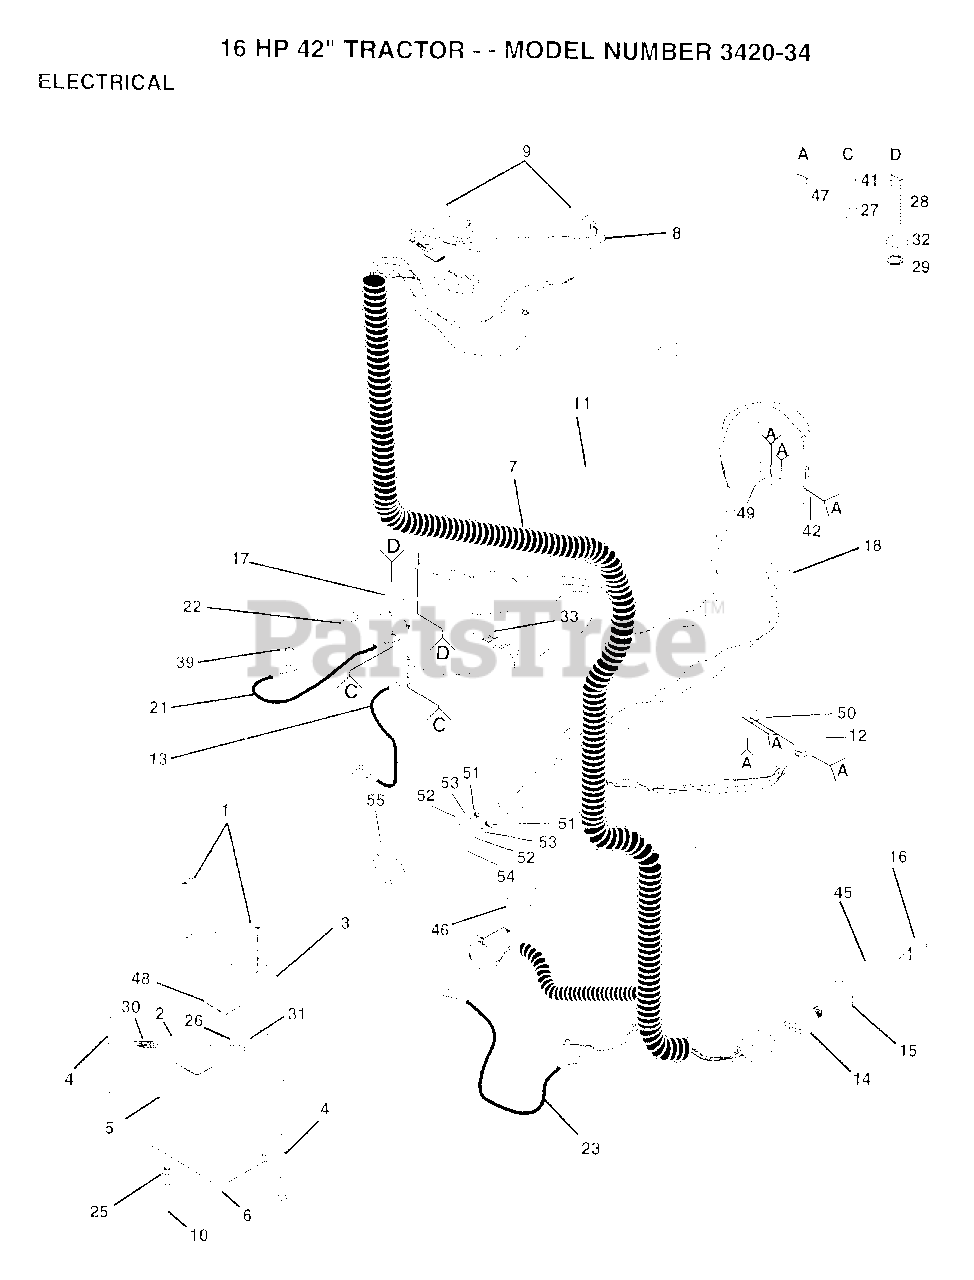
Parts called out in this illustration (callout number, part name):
2	WASHER
4	BOLT
6	"TRAY T, BATTERY"
7	HARNESS.IGN.B&S
8	"HARNESS,LIGHT SOC"
10	"DRAIN TU T, BATT"
11	WIRE TIE
12	SWITCH INTERLOCKT
13	"CABLE T, BATTERY"
15	NUT IGNITION
16	KEY
18	SWITCH LT
21	CABLE ASM.
23	CABLE T
25	HOSE CLAMP T
26	LOCKWASHER
27	NUT
28	BOLT
29	NUT
30	BOLT LT
33	FUSE HYT
39	LOCKWASHER
42	SWITCH-INTER. GT
46	SWITCH SEAT
47	SCREW
48	"CAP,BATTERY "
49	BRACKET LT
50	SWITCH BRACKET
52	WASHER
55	AMMETER T
